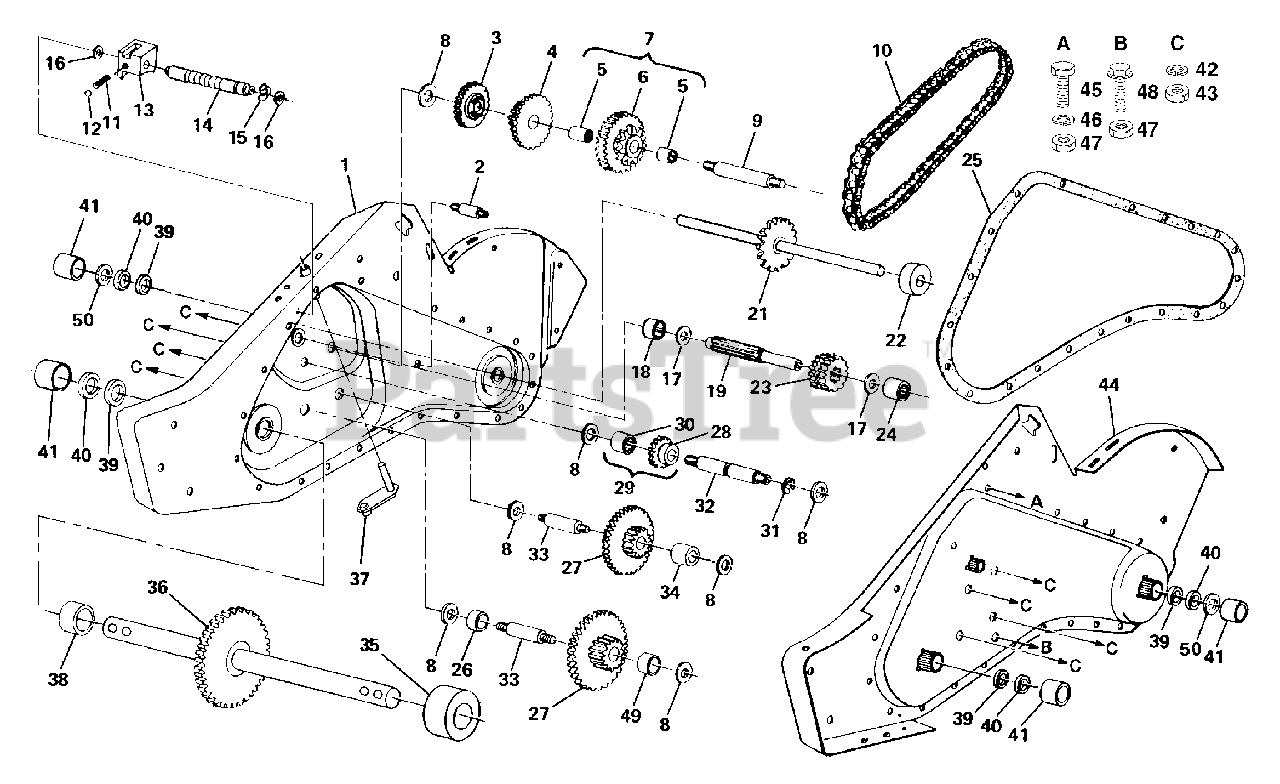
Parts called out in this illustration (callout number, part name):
1	Gearcase Assembly, R.H., with Bearing
2	Bolt, Upset
3	Gear, Reverse
4	Gear, Cluster, Red., 1st and 2nd
5	Bearing, Needle
6	Sprocket Assembly, Tine
7	Sprocket Assembly with Bearings
9	Shaft, Reduction, 1st
10	Chain, Roller, 60P
11	Spring, Shift, Fork
12	Ball, Steel
13	Fork, Shift
14	Shaft, Shift
16	Washer, Seal
17	Race, Bearing, Thrust, 5/8 I.D.
18	Bearing, Needle
19	Shaft, Input
21	Shaft Assembly, Tine
22	Spacer 1.008 x 1-3/4 x .645
23	Pinion, Input
24	Bearing, Needle
25	Gasket, Gearcase
26	Spacer .765 I.D. x 1.12 x 5/8
27	Gear, Cluster, Red., 2nd and 3rd
28	Gear, Reverse Idler
29	Gear Assembly, Reverse Idler
30	Bearing, Needle
32	Shaft, Reverse Idler
33	Shaft, Reduction, 2nd
34	Spacer .765 I.D. x 1-1/8 x 1-3/8
35	Spacer, Ground Drive, L.H.
36	Shaft Assembly, Ground
37	Arm Assembly, Shift
38	Spacer, Ground Drive, R.H.
39	Seal, Oil
40	Seal, Ring, Rubber
41	Cup, Formed
42	Washer, Lock 7/16
43	Nut, Hex 7/16-20
44	Gearcase Assembly, L.H., with Bearing
45	Bolt, Hex Head 5/16-18 x 3/4
46	Washer, Lock 5/16
47	Nut, Hex Head 5/16-18
48	Screw, Whiz-Lock 5/16-18 x 4
49	Spacer .765 I.D. x 1.12 x 3/4
50	Ring, Spiral
